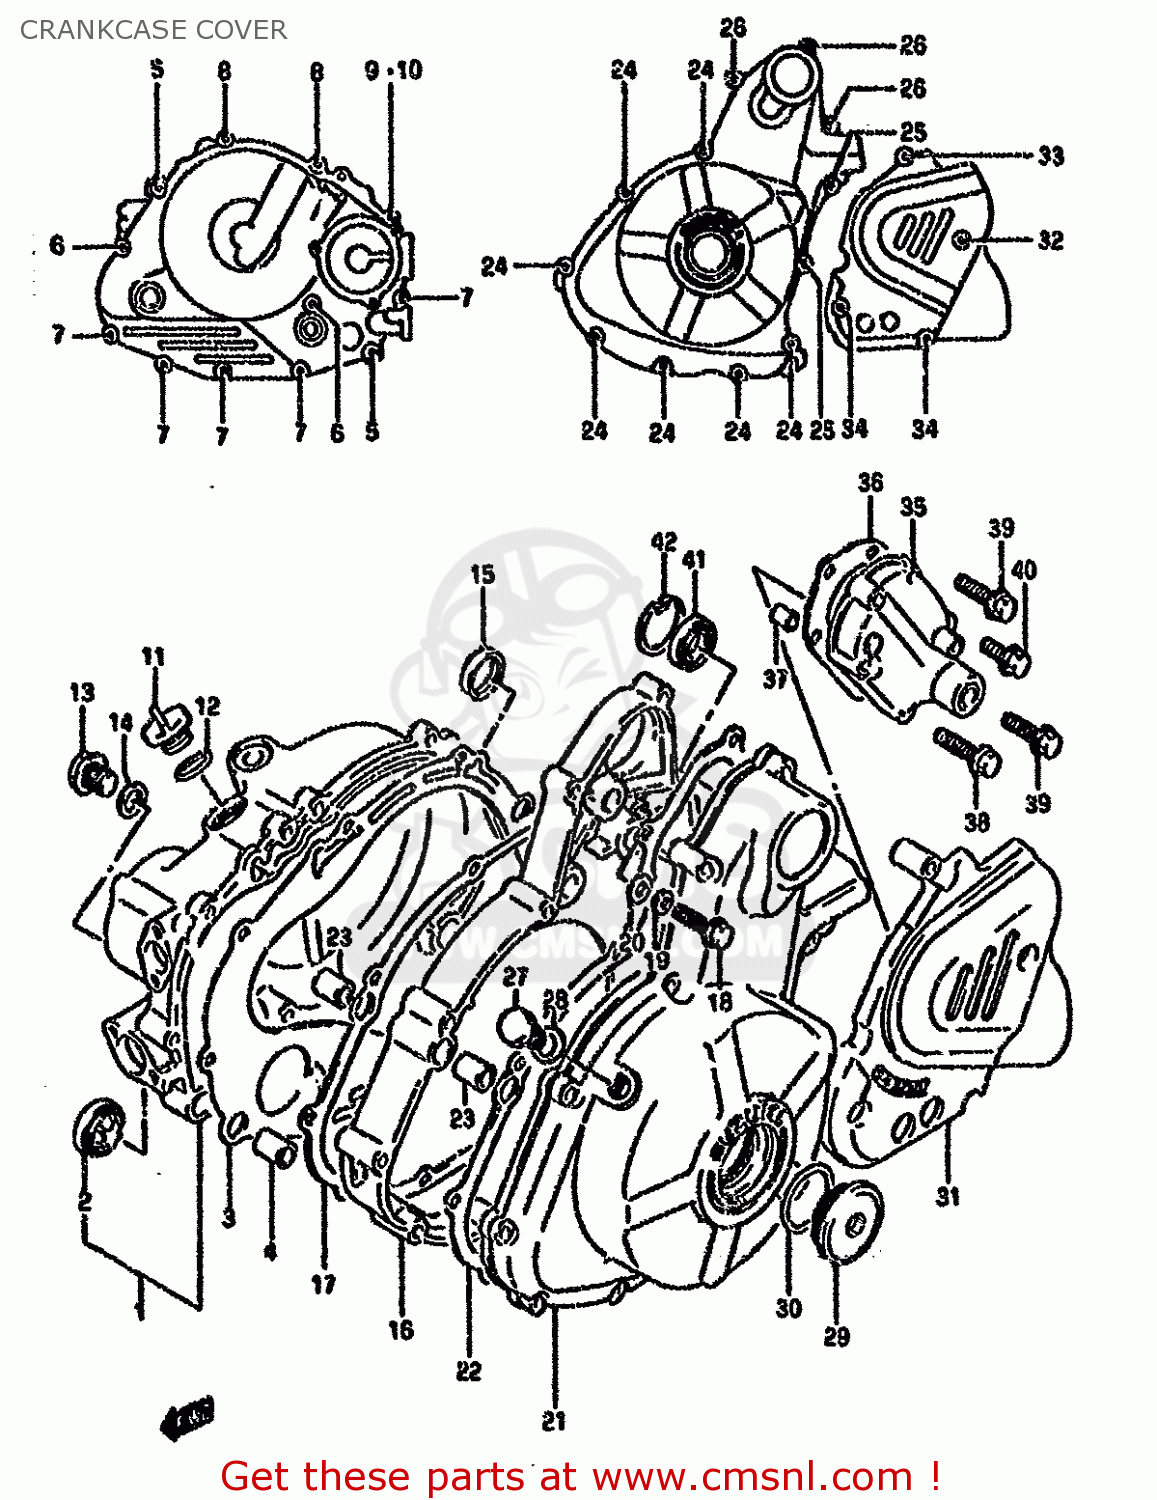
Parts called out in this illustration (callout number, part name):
1	COVER,CLUTCH
2	LENS,OIL LEVEL CHECK
3	GASKET,CLUTCH COVER (NAS)
4	PIN
5	BOLT
6	BOLT
7	BOLT
8	BOLT
9	BOLT 6X25
10	WASHER
11	PLUG
12	O RING(D:3.1,ID:16.8)
13	PLUG(14X12)
14	GASKET(14X19.2X2) (NAS)
15	PLUG,CLUTCH COVER KICK
16	COVER,GENERATOR INNER
17	GASKET,MAGNETO COVER (NAS)
18	BOLT 6X30
19	LOCK WASHER
20	WASHER
21	COVER,GENERATOR OUTER
22	GASKET,GENERATOR OUTER COVER (NAS)
23	PIN
24	BOLT
25	BOLT
26	BOLT
27	PLUG(12X9)
28	GASKET(12.1X16.2X3.7) (NAS)
29	PLUG
30	O RING(D:3.1,ID:32.7)
31	COVER,ENGINE SPROCKET
32	BOLT
33	BOLT
34	BOLT
35	COVER,GEAR SHIFT
36	GASKET,GEAR SHIFT COVER (NAS)
37	PIN
38	BOLT
39	BOLT 6X30
40	SCREW
41	BEARING(12X28X8)
42	CIRCLIP
